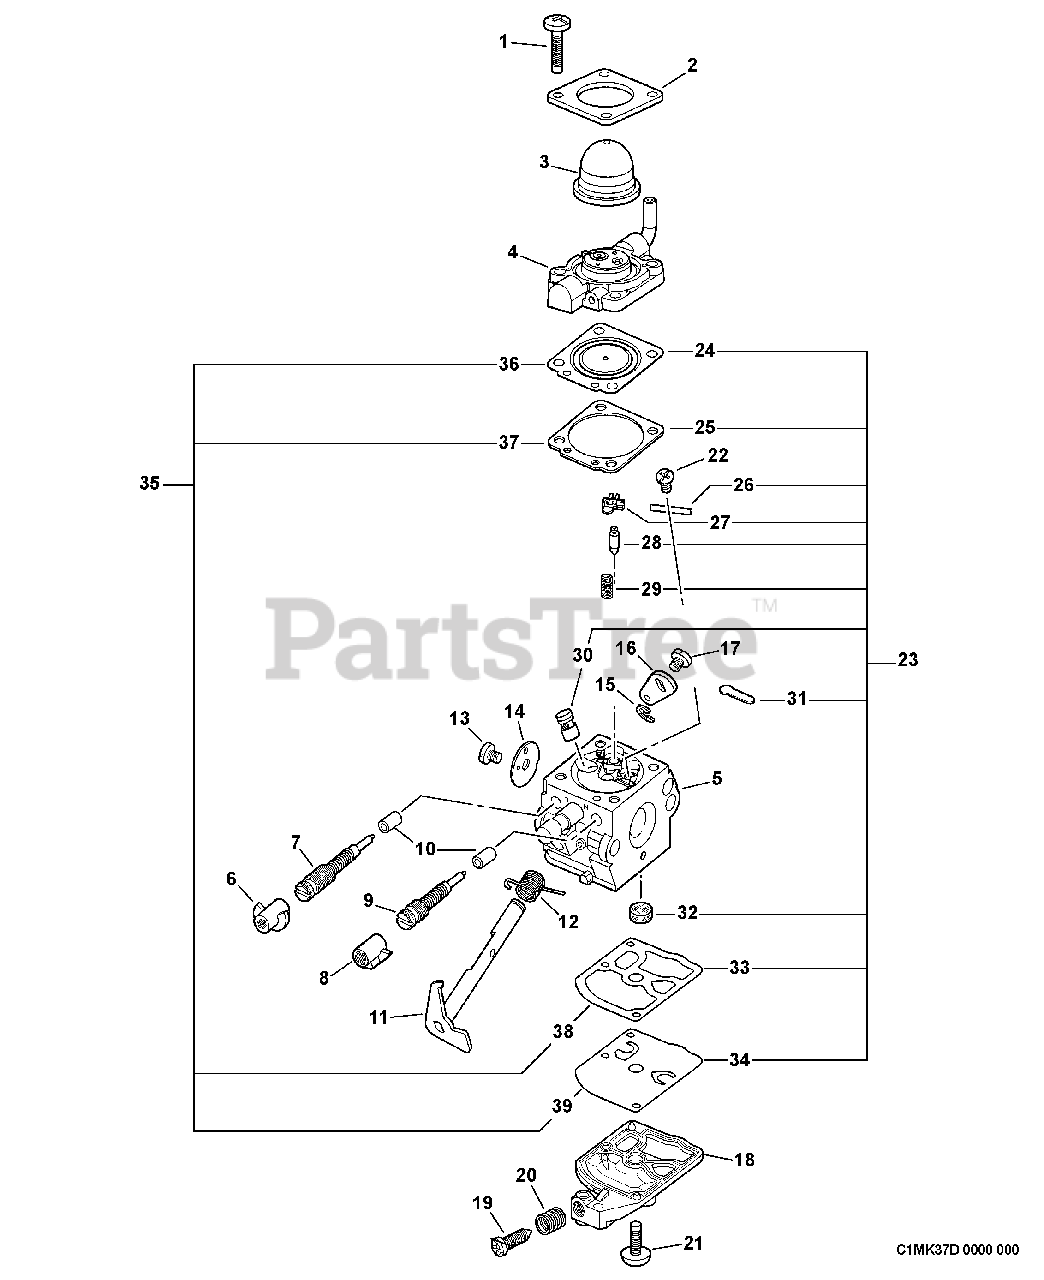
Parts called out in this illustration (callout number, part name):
2	RETAINER, PURGE BULB
3	BULB, PURGE
4	BODY ASSY, PURGE
5	BODY, CARBURETOR
6	CAP, LIMITER - WHITE
7	NEEDLE, LOW SPEED
8	CAP, LIMITER
9	NEEDLE, HIGH SPEED
10	RETAINER
11	SHAFT, THROTTLE
12	SPRING, THROTTLE RETURN
13	SCREW 3×4.5
14	VALVE, THROTTLE PB-46HT/1E
16	LEVER, THROTTLE
18	COVER, PUMP
20	SPRING, IDLE ADJUST
23	REPAIR KIT
24	DIAPHRAGM, METERING
25	GASKET, METERING
26	PIN, METERING LEVER
27	LEVER, METERING
28	VALVE, INLET NEEDLE
29	SPRING, METERING LEVER
30	NOZZLE, CHECK VALVE
31	PLUG, WELCH
32	STRAINER
33	DIAPHRAGM, PUMP
34	GASKET, PUMP
35	GASKET / DIAPHRAGM KIT
36	DIAPHRAGM, METERING
37	GASKET, METERING
38	DIAPHRAGM, PUMP
39	GASKET, PUMP
